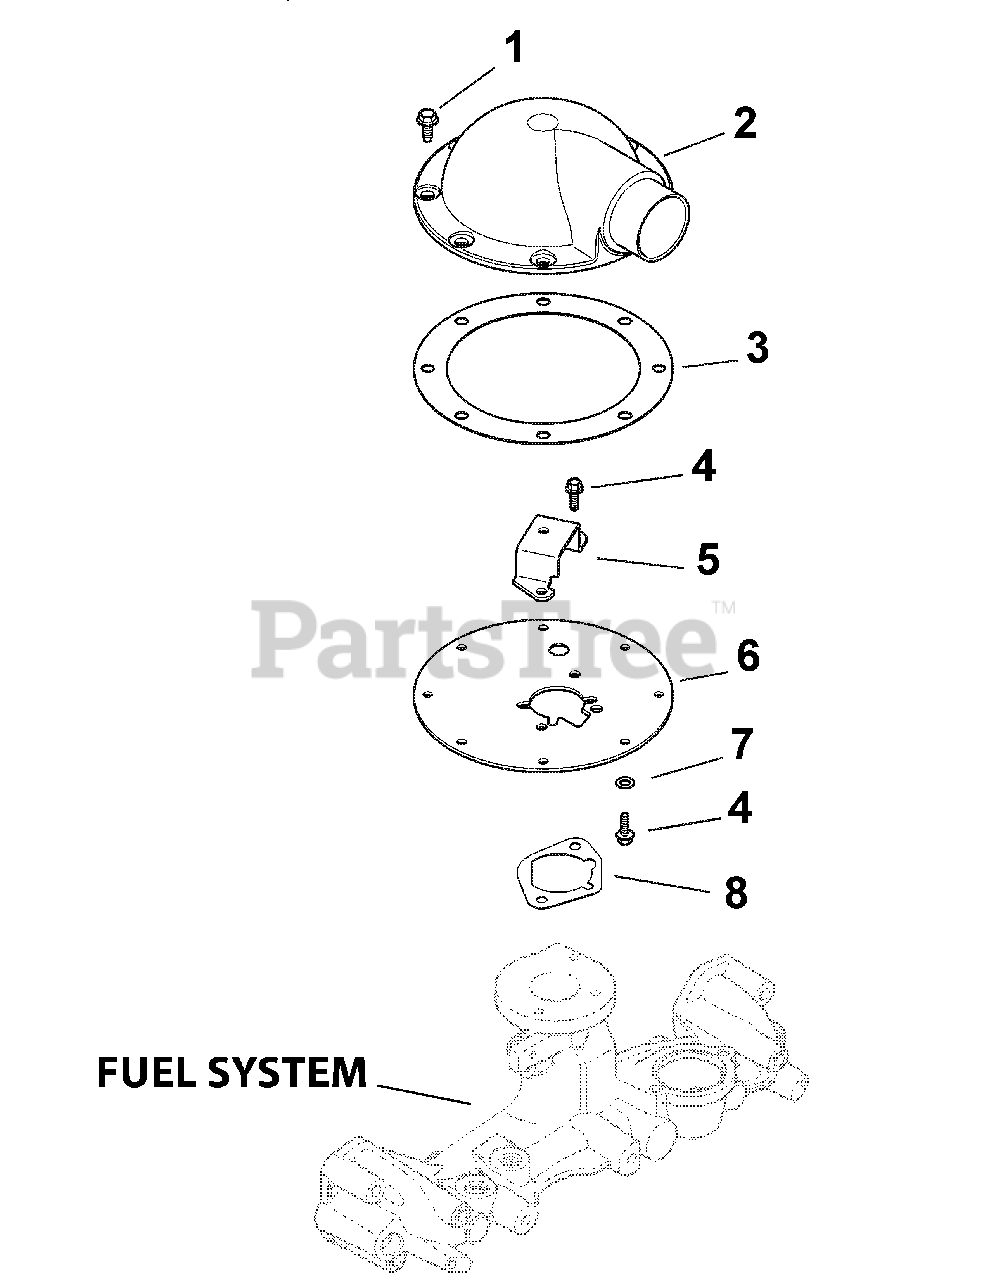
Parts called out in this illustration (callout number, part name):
1	Screw, Flg Thd Frm, M6x1.0x16
2	Adapter, Air Intake
3	Gasket, Air Cleaner Adapter
4	Screw, Hvy Flg, M5 x .8 x 16
5	Bracket, Air Cleaner
6	Adapter, Plate
8	Gasket, Air Cleaner Base
